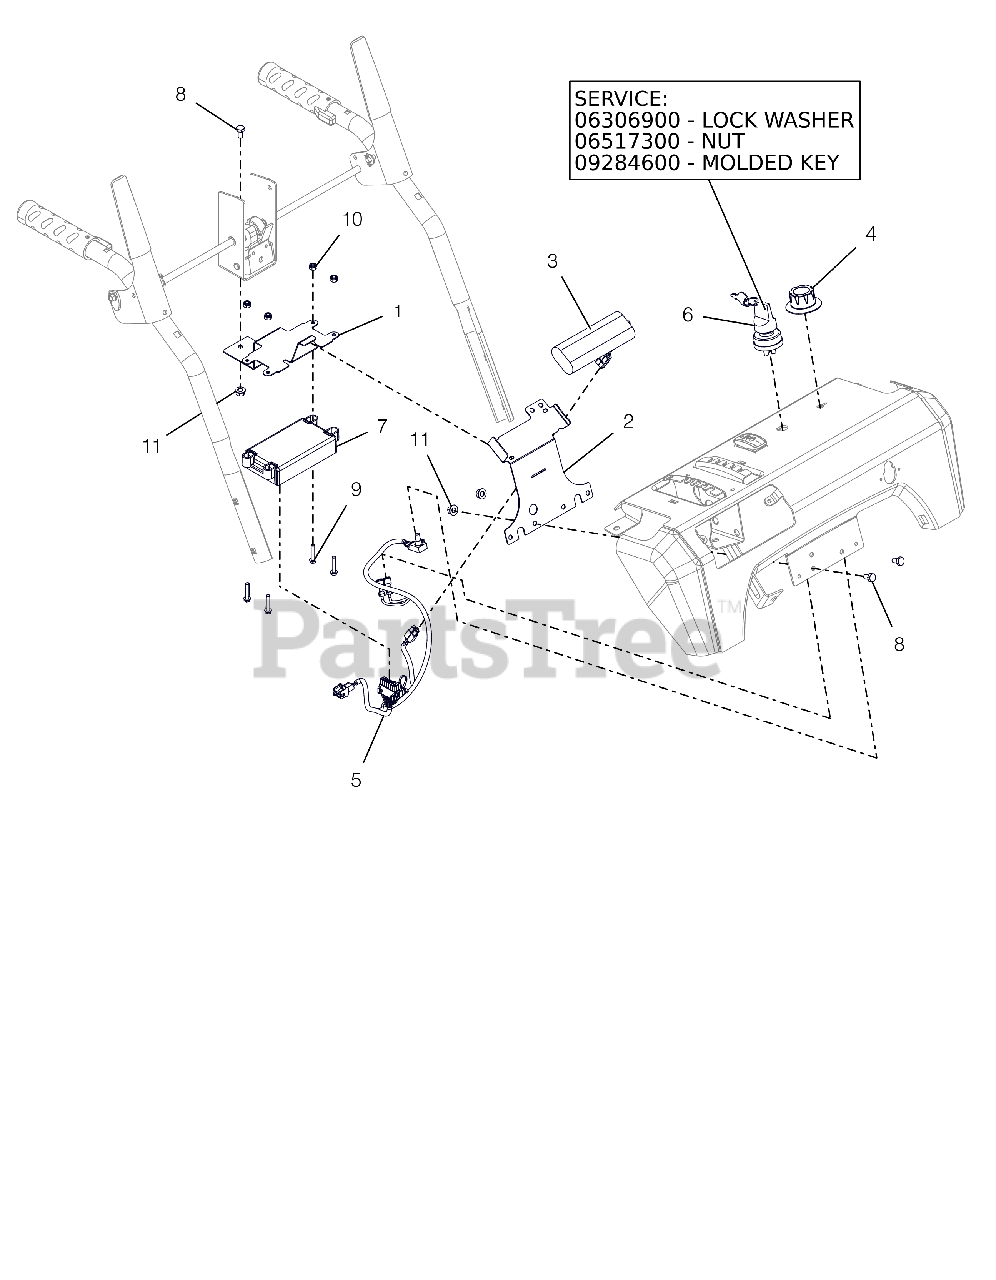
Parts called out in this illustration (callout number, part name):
1	BRACKET, ENGINE EFI-LCT LOWER
2	BRACKET, ENGINE EFI-LCT UPPER
3	BATTERY, SNOW EFI - 7.2V
4	KNOB, CONTROL - 2.063 ID
5	HARNESS,WIRE - EFI ECU
6	IGNITION SWITCH ASM - 2 POS
6	WSHR-LK-INT .625X.045 YWZC
6	NUT-PANEL .625-32 GRECO
6	KEY W/ SHIELD
7	ECU SERVICE LCT/CSI - 306CC
8	@BLT-HEX .25-20X.50 GR5 YWZC
9	@SCR-MCH 10-24X1.00 HWH YWZC
10	@NUT-LK-NYL 10-24 W/INSRT YWZC
11	@NUT-LK-TOP-FLG .25-20 YWZC
